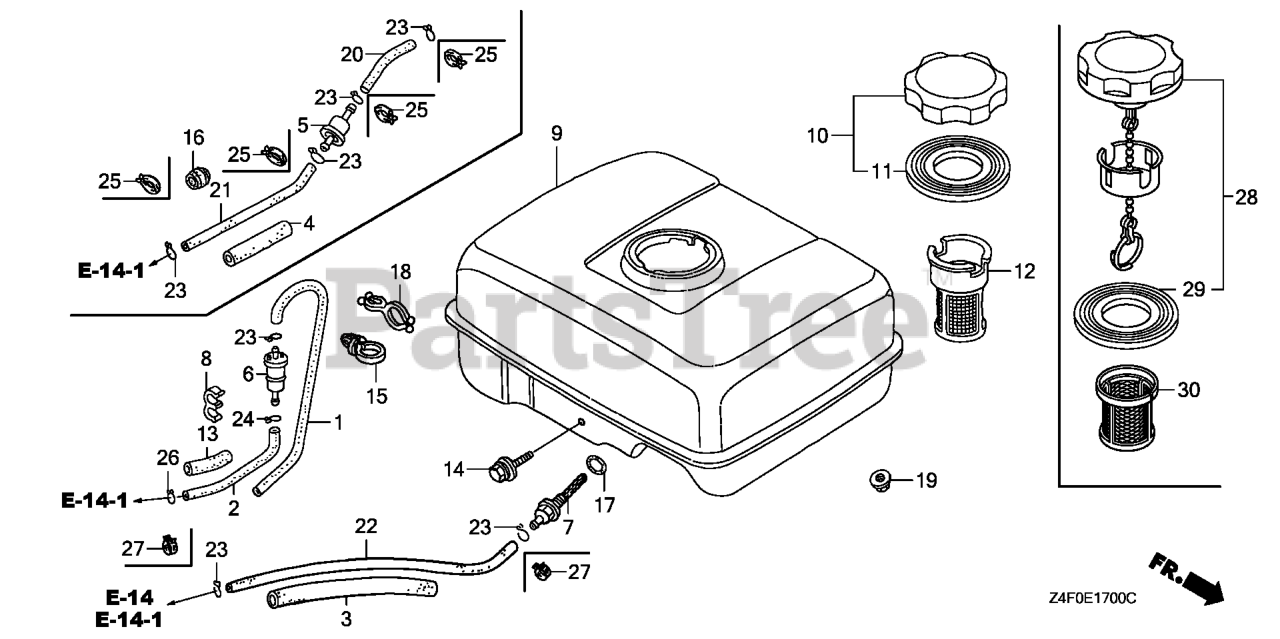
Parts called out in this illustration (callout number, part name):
3	RUBBER, SUPPORTER (107MM)
7	JOINT, FUEL TANK
9	TANK, FUEL *NH31* (MCKINLEY WHITE)
14	BOLT, FLANGE (6X29)
17	O-RING (14MM) (ARAI) Use up to Engine SN 2949254.
19	NUT, FLANGE (6MM)
22	TUBE, FUEL (4.5X140) (FKM)
22	TUBE, FUEL (4.5X140)
27	CLIP, TUBE (D8)
28	CAP, FUEL FILLER
29	GASKET, FUEL FILLER CAP
30	FILTER, FUEL (FROM 1204807)
